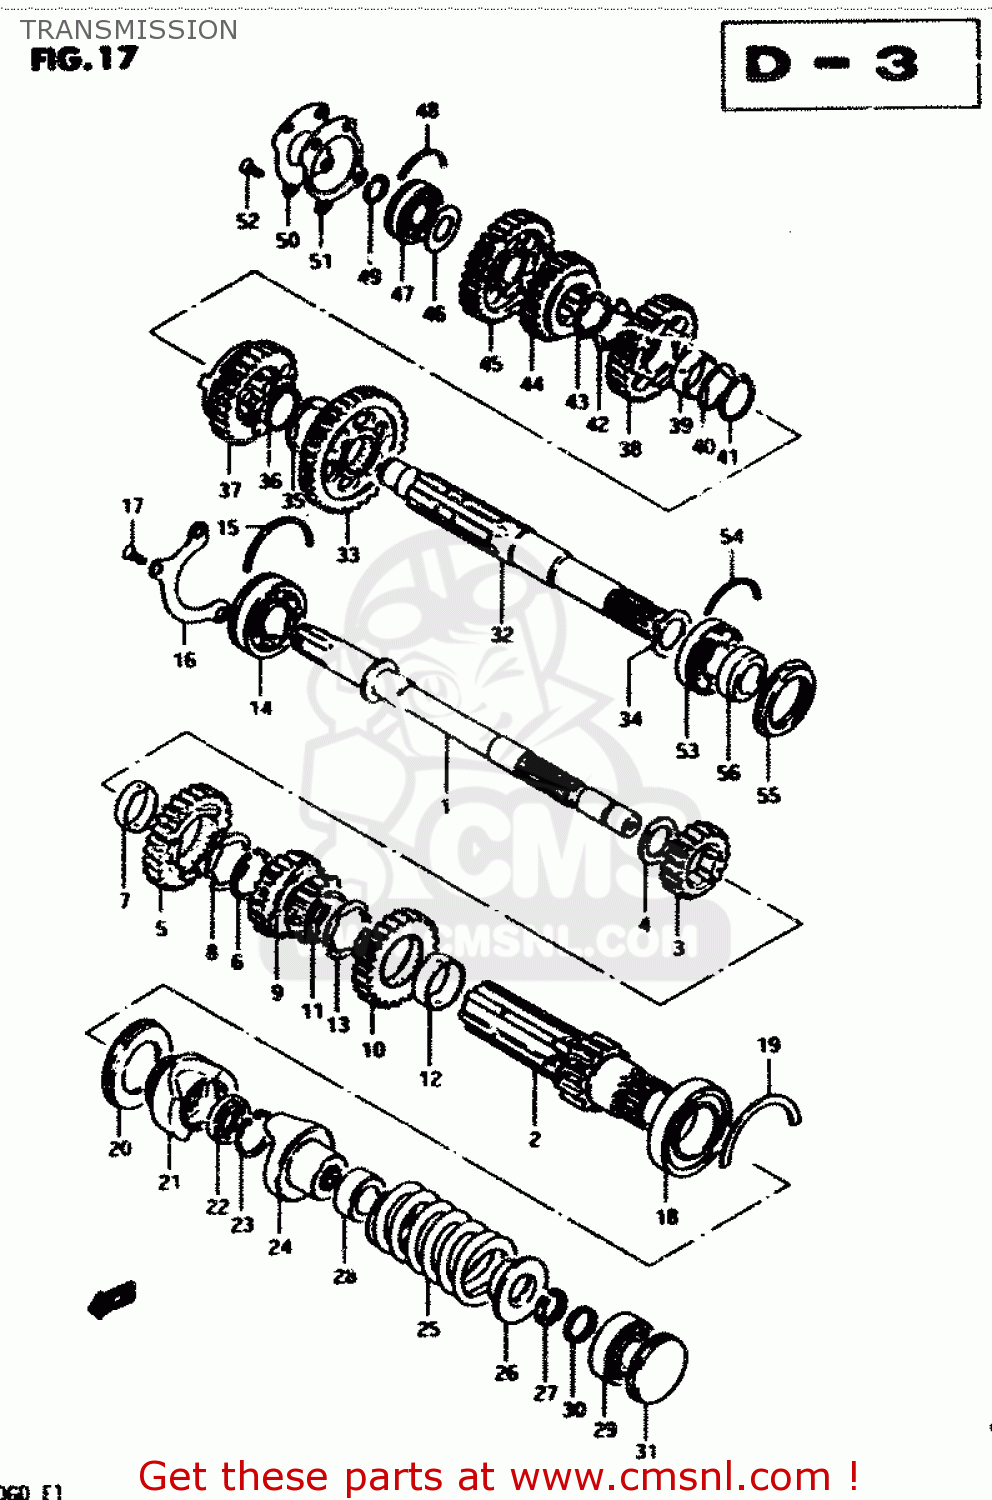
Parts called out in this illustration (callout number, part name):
1	SHAFT,COUNTER
2	SHAFT,OUTER COUNTER
3	GEAR,SECOND DRIVE
4	WASHER (21X35X2)
5	GEAR,5TH DRIVE(NT:26)
6	RING,SNAP
7	SPACER,DRIVE GEAR
8	LOCK WASHER,5TH DR GEAR SPACER
9	GEAR,THIRD DRIVE
10	GEAR,FOURTH DRIVE
11	RING,SNAP
12	SPACER,DRIVE GEAR
13	LOCK WASHER,5TH DR GEAR SPACER
14	BEARING(25X62X17)
15	C-RING
16	RETAINER,CNTR SHAFT BEARING
17	SCREW
18	BALL BEARING 32X58X13
19	C-RING
20	SEAL,OIL(40X58X7)
21	DOG,OUTPUT CAM
22	SEAL,OIL(20.6X31X6)
23	CIRCLIP
24	DOG,INPUT CAM
25	SPRING
26	STOPPER,CAM DOG SLIDING
27	STOPPER,CAM DOG
28	GUIDE,CAM DOG SPRING
29	BEARING
30	SPACER (17X21X3.5)
31	PLUG
32	SHAFT,DRIVE
33	GEAR,FIRST DRIVEN
34	WASHER, LH
35	WASHER,LOCK
36	CIRCLIP
37	GEAR,FOURTH DRIVEN
38	GEAR,THIRD DRIVEN
39	BUSH,3RD DRIVEN GEAR
40	WASHER,LOCK
41	CIRCLIP
42	WASHER
43	WASHER,LOCK
44	GEAR,FIFTH DRIVEN
45	GEAR,SECOND DRIVEN
46	WASHER
47	BEARING(20X47X14)
48	C RING
49	CIRCLIP
50	PLATE,DRIVESHAFT
51	GASKET,DRIVESHAFT PLATE (MCA)
52	SCREW
53	BEARING
54	C RING
55	SEAL,OIL(35X52X6)
56	SPACER,DRIVESHAFT,LEFT
